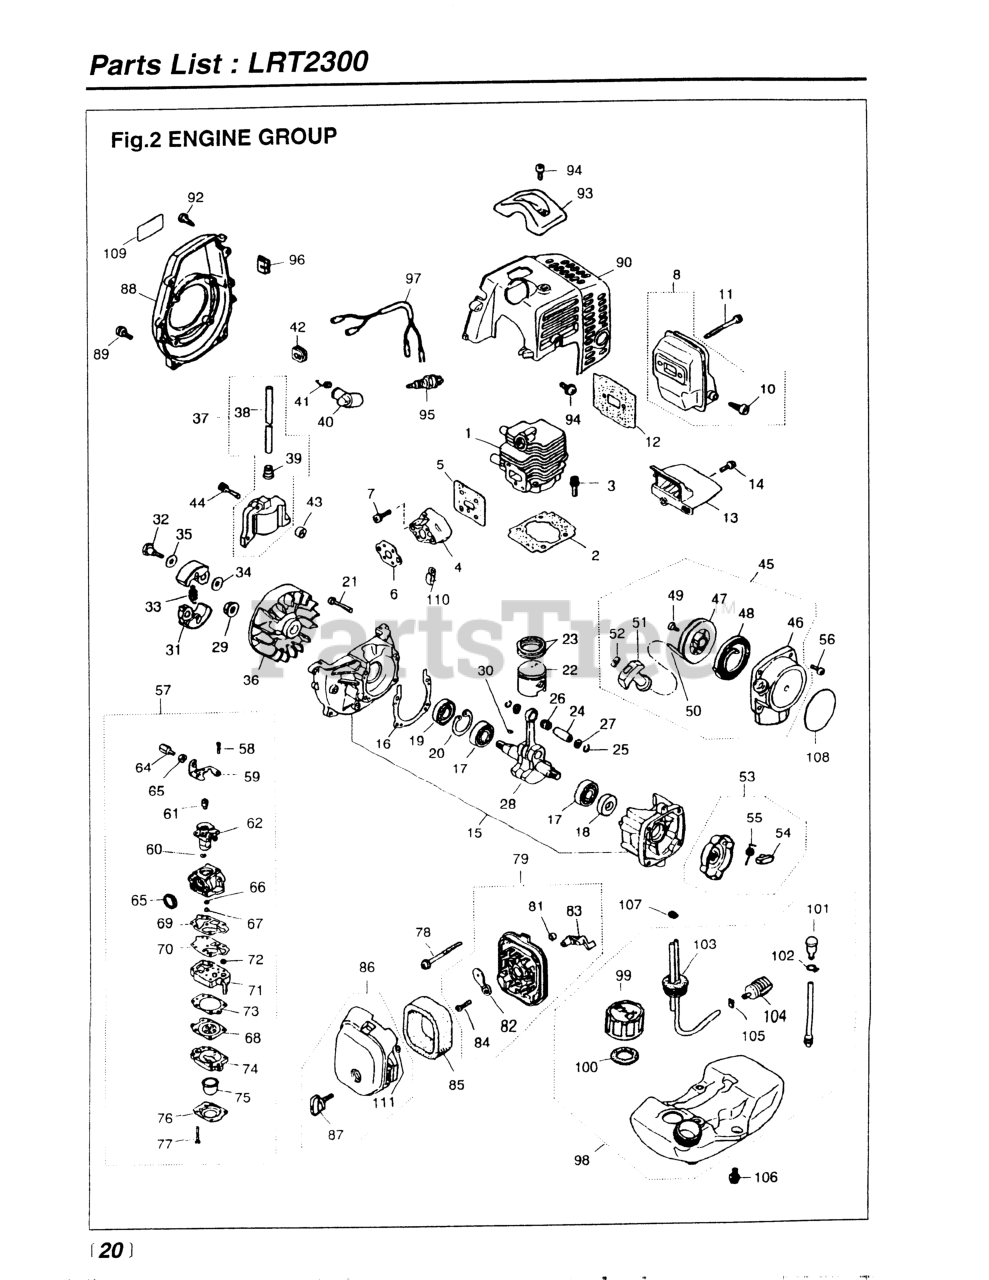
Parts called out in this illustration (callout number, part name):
1	CYLINDER
3	BOLT, M5 X 22
7	SCREW, M5X20 (RPLS.1400-75510)
8	MUFFLER ASSY (RPLS 5501- )
11	BOLT, M5 x 50
12	GASKET, MUFFLER
14	SCREW, M4 X 16
15	CRANKCASE
17	BEARING
18	SEAL, OIL (RPLS 1100-21210)
19	SEAL, OIL (RPLS 1140-21220)
20	RING, SNAP, M28 x 1.2
21	BOLT, M5 X 30
22	PISTON (REPLACES 1140-41110)
23	RING, PISTON (RPLS 1850-41210)
24	PIN, PISTON 5x8x26
25	RING, SNAP (RPLS 1101-41320)
27	WASHER
28	CRANKSHAFT (RPLS 1850-42000)
30	KEY
32	BOLT
33	SPRING, CLUTCH (RPLS-51220)
34	WASHER, FLAT (USE 182303)
37	COIL ASSY (RPLS 5500-71200)
38	CORD
39	CAP
41	SPRING
42	GROMMET
43	SPACER (RPLS -71260)
44	BOLT
45	RECOIL ASSEMBLY
46	CASE
47	REEL
48	SPRING, SPIRAL
49	SCREW (RPLS -75150)
51	KNOB
52	PLATE, STOPPER
53	PULLEY ASSY (RPLS -75210)
54	RATCHET (RPLS 1850-75220)
55	SPRING, RETURN
56	SCREW, M4 X 16
57	CARBURETOR
58	SCREW
60	RING
61	SWIVEL
62	VALVE ASSY
64	NUT, CABLE ADJUSTER
65	RING, PACKING
66	RING, O
67	JET
68	DIAPHRAGM (USE 4810-81260)
69	GASKET, PUMP
70	DIAPHRAGM
71	BODY, PUMP
73	GASKET, DIAPHRAGM
74	BODY, PURGE
75	PUMP, PRIMING
76	COVER, PUMP
77	SCREW
78	SCREW, M5 x 60
79	BODY-A (RPLS -82101)
81	SLEEVE
82	PLATE, CHOKE (RPLS-82130)
83	LEVER, CHOKE
84	SCREW (REPLACES 50030272)
85	ELEMENT
87	KNOB (RPLS -82220)
88	COVER, FAN (RPLS-31110)
89	SCREW, M5X20 (RPLS.1400-75510)
92	SCREW, HOUSING
93	GUARD, PLUG
94	SCREW,M5 X 14 (RPLS 1400-15510
97	CORD COMP (RPLS -73200)
99	CAP (RPLS -85200)
100	PACKING
102	CLIP
103	PIPE COMPLETE
104	FILTER (RPLS 1850-85300)
105	CLIP (REPLACES 2841-31280)
106	SCREW
107	CLIP
108	LABEL, RECOIL
110	CLAMP
111	RING
NI	SCREW, CABLE ADJUSTER
NI	SCREW, M5 x 12
